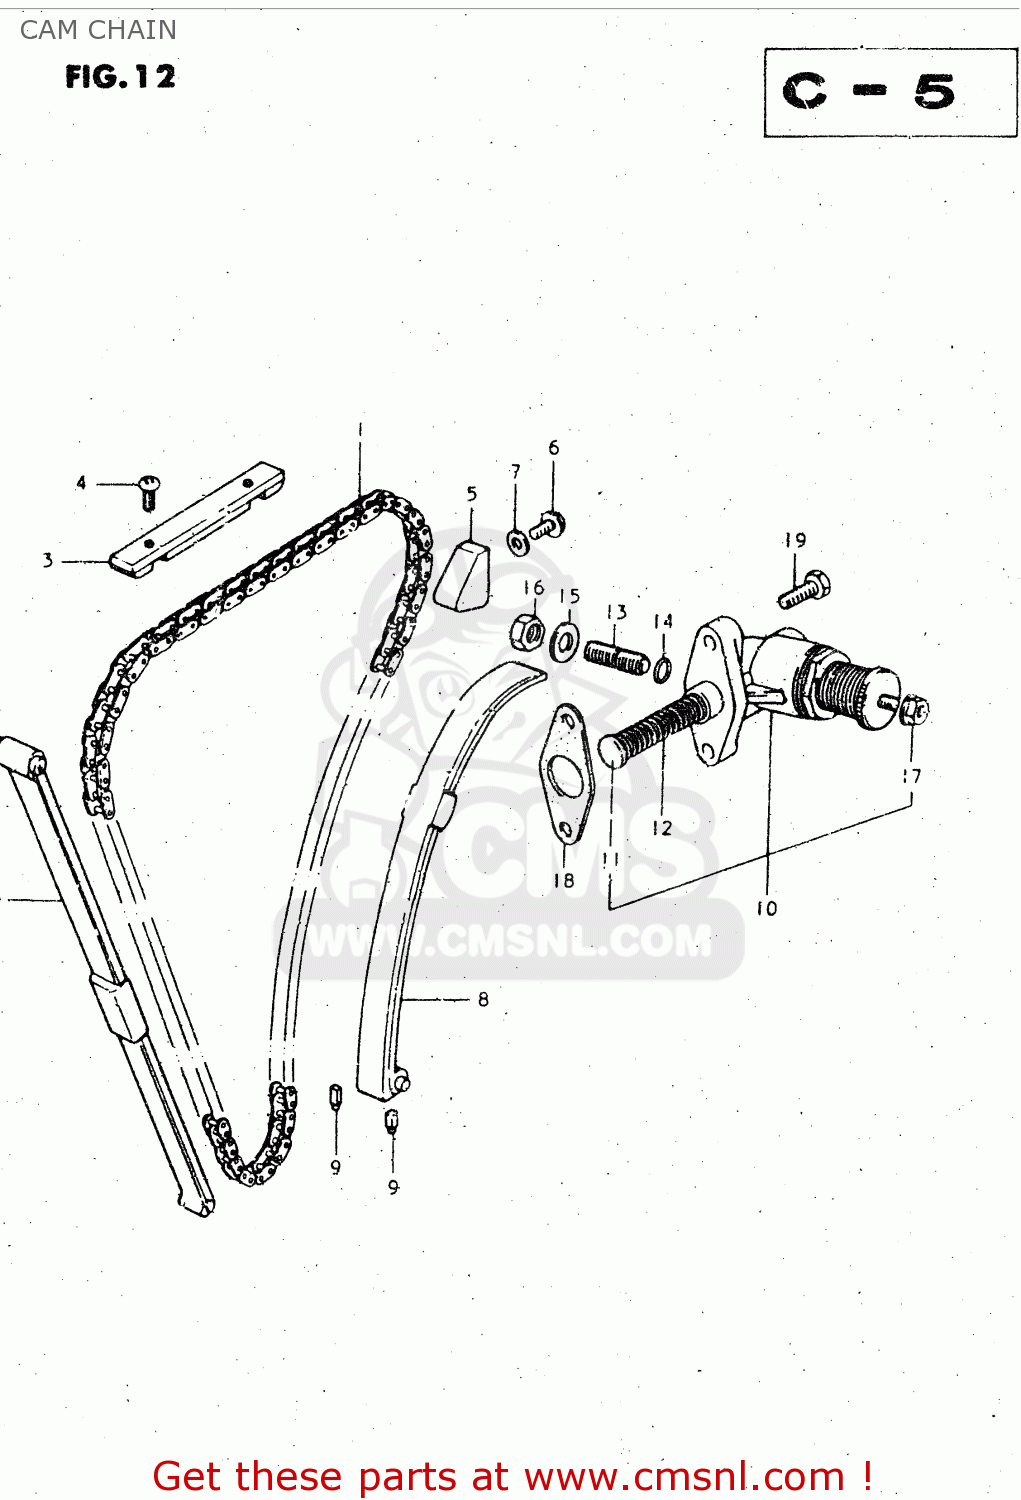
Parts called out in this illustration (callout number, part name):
1	CHAIN,CAMSHAFT DRIVE(120L)
2	GUIDE,CAM CHAIN NO.1
3	GUIDE,CAM CHAIN NO.3
4	SCREW
5	GUIDE,CAM CHAIN
6	BOLT
7	GASKET (NAS)
8	TENSIONER,CAM CHAIN
9	CUSHION,CAM CHAIN TENSIONER
10	ADJUSTER ASSEMBLY,TENSIONER
11	ROD,PUSH
12	SPRING
13	SCREW
14	O-RING
15	WASHER
16	NUT
17	NUT
18	GASKET,TENSIONER ADJUSTER (MCA)
19	SCREW (6X25)
